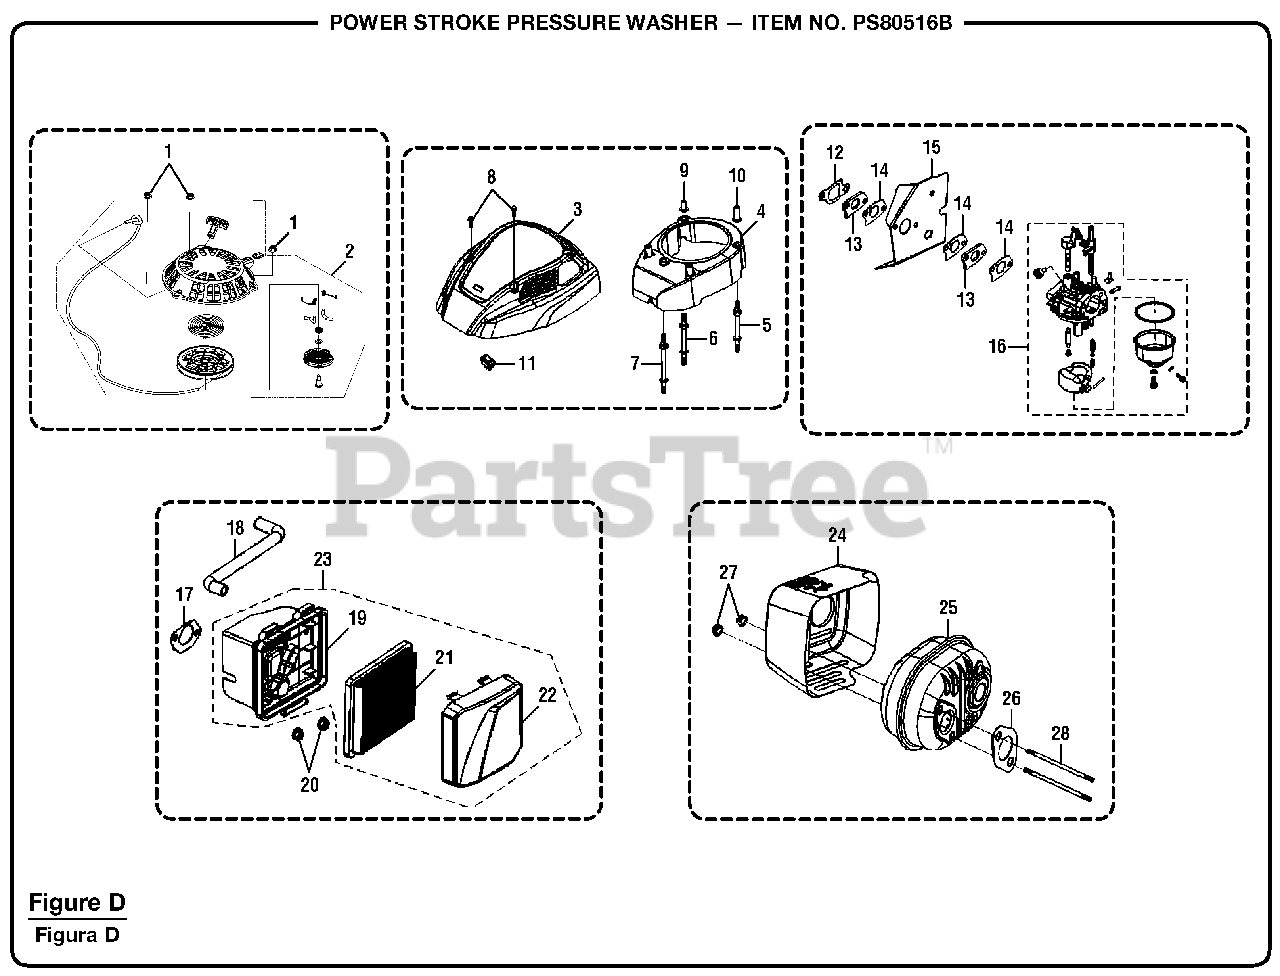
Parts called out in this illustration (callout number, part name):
2	Recoil Starter Assembly
11	Stop Engine Switch
12	Insulator Plate Gasket
13	Carburetor Insulator Plate
14	Carburetor Gasket
15	Carburetor Insulator Gasket
16	Carburetor Assembly
17	Air Cleaner Gasket
19	Air Cleaner Case
21	Air Clean Element Assembly
22	Air Cleaner Cover
24	Muffler Outer Cover
25	Muffler Assembly
26	Exhaust Outlet Gasket
